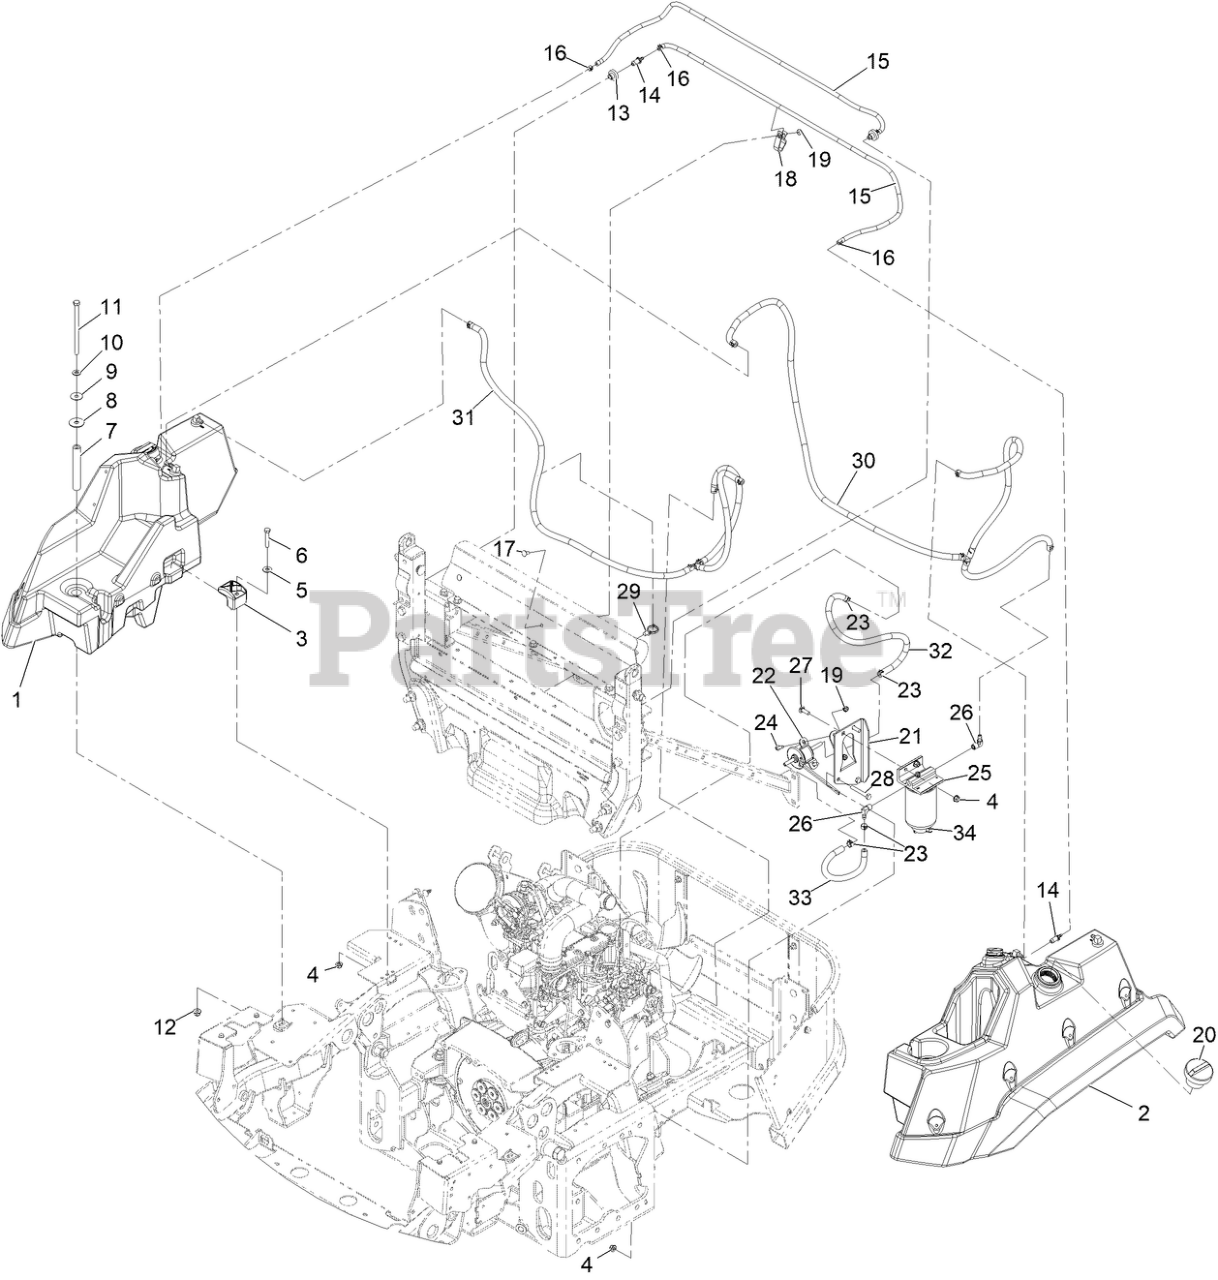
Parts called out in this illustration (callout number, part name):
1	RH FUEL TANK ASM
2	ASM-FUEL TANK, LH
4	NUT-HF, NI
5	WASHER-FLAT
6	SCREW-HH
7	TUBE-SPACER
8	WASHER-RUBBER
9	WASHER-PLAIN
10	WASHER-FLAT
11	SCREW-HH
12	NUT-HF, NI
13	BUSHING
14	FITTING-ORIFICE, STRAIGHT
15	HOSE-VENT, TANK
16	CLAMP-HOSE
17	SCREW-CARR
18	CLAMP-HOSE
20	CAP-FUEL, DIESEL LOW OR ULTRA LOW SULFUR
21	BRACKET-FILTER AND PUMP,
22	PUMP-FUEL, ELECTRIC
23	CLAMP-HOSE
24	SCREW-HWH
25	ASM,FUEL FILTER W/HEAD
26	FITTING-HYD, 90
27	SCREW-CARR
28	SCREW-HH
29	CLIP-TIE
30	LINE-FUEL, SUCTION
31	LINE-FUEL, RETURN
32	HOSE-FUEL
33	HOSE-FUEL
34	FILTER-FUEL
